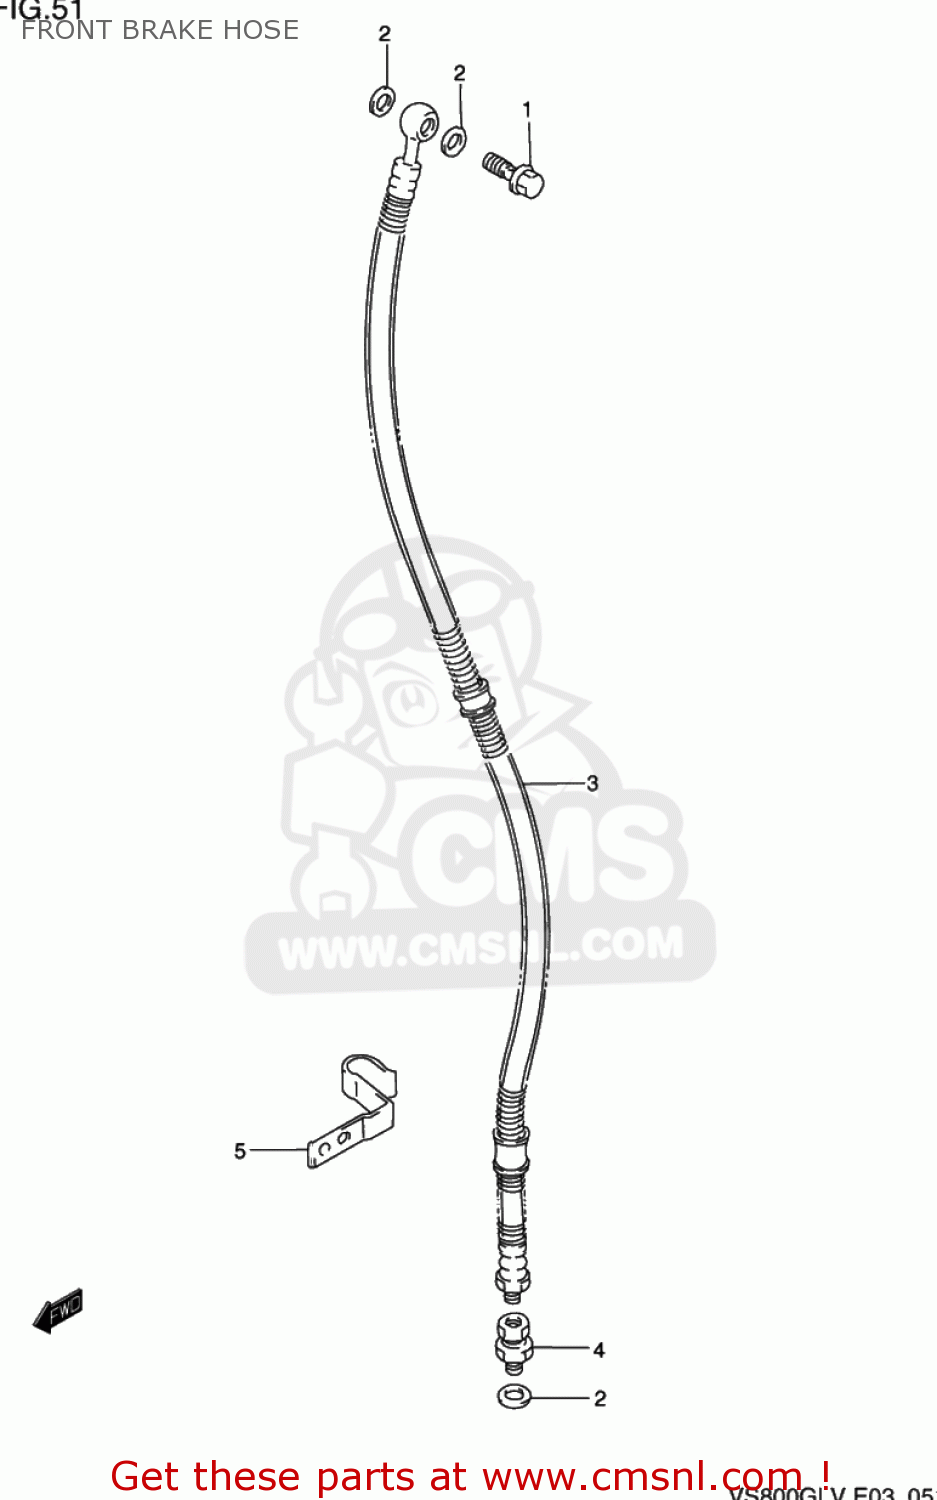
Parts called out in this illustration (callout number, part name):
1	BOLT UNION
2	WASHER(10X15X1.5)
3	HOSE,FR BRAKE
4	ADAPTER,BRAKE HOSE
5	GUIDE,BRAKE HOSE
